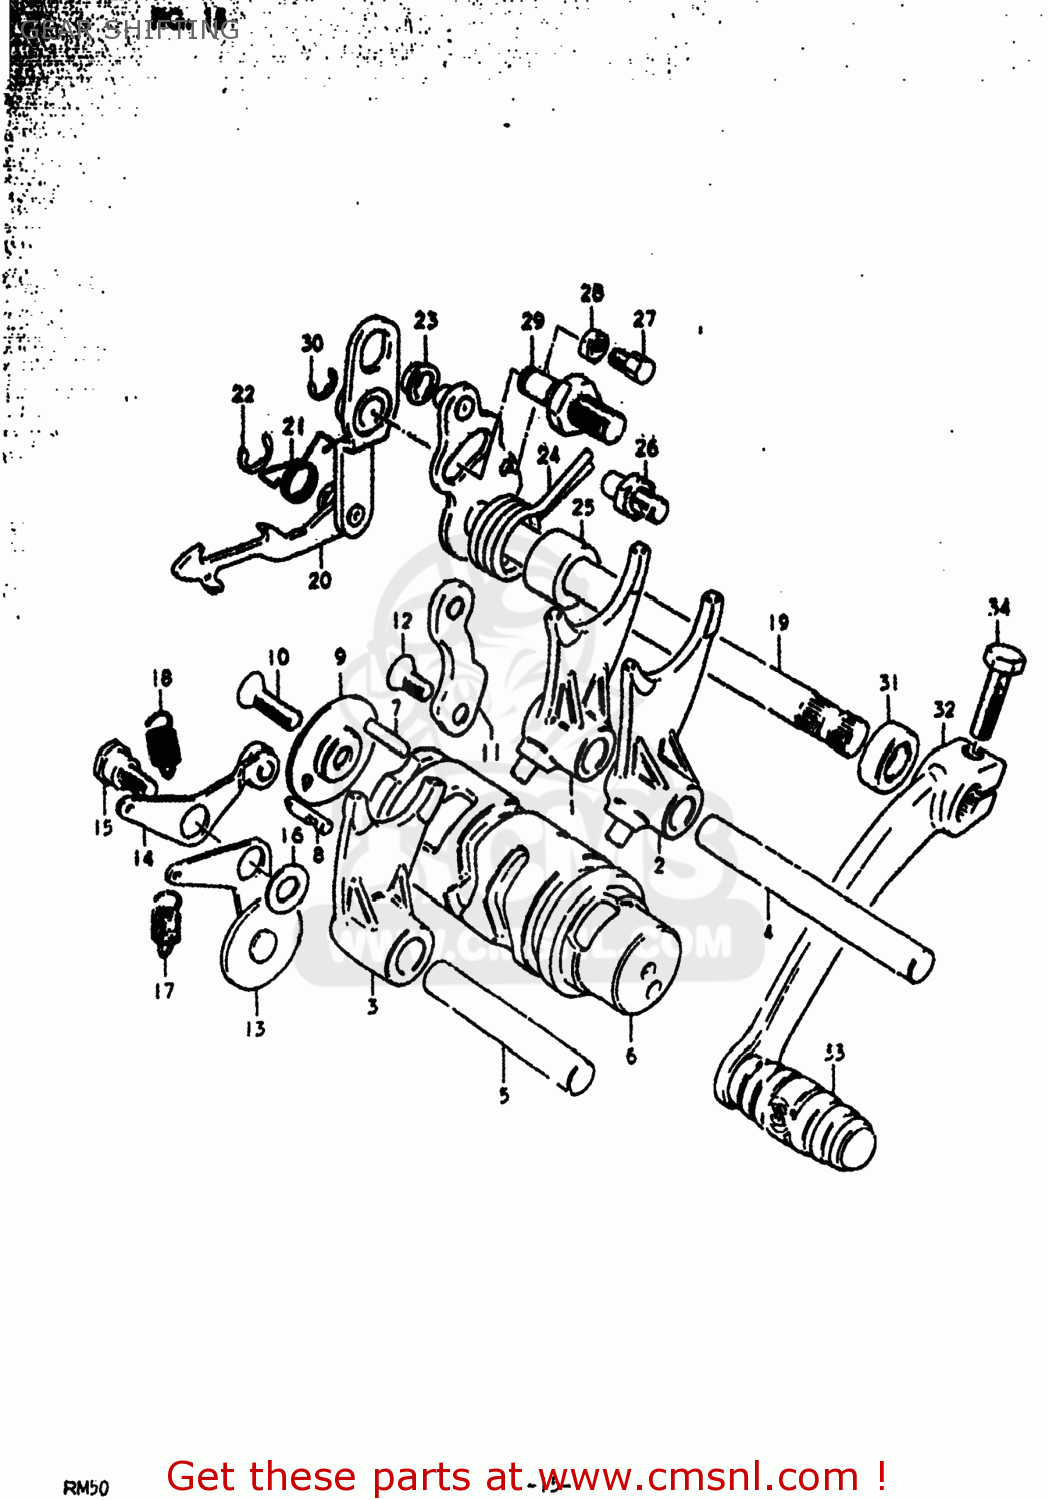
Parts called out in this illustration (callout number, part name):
1	FORK,GEAR SHIFT NO.1
2	FORK,GEAR SHIFT NO.2
3	FORK,GEAR SHIFT NO.3
4	SHAFT,GEAR SHIFT FORK
5	SHAFT,GEAR SHIFT FORK
6	CAM,GEAR SHIFT
7	PIN(4X15.8)
8	PIN
9	RETAINER,GEAR SHIFT CAM DR PIN
10	SCREW
11	GUIDE,GEAR SHIFT CAM
12	SCREW
13	STOPPER,GEAR SHIFT CAM
14	STOPPER,GEAR SHIFT CAM NEUTRAL
15	BOLT(6X18.3)
16	WASHER
17	SPRING
18	SPRING
19	SHAFT,GEAR SHIFT
20	PAWL,GEAR SHIFTING
21	SPRING
22	E RING
23	SPACER(7X10X5)
24	SPRING
25	SPACER(12X20X15.3)
26	STOPPER,GEAR SHIFT CAM
27	BOLT,GEAR SHAFT RETURN SPR SET
28	NUT 6MM
29	STOPPER,GEAR SHIFT CAM
30	E RING 6MM
31	OIL SEAL
32	LEVER ASSEMBLY,GEAR SHIFTING
33	RUBBER,GEAR SHIFT PEDAL
34	BOLT
